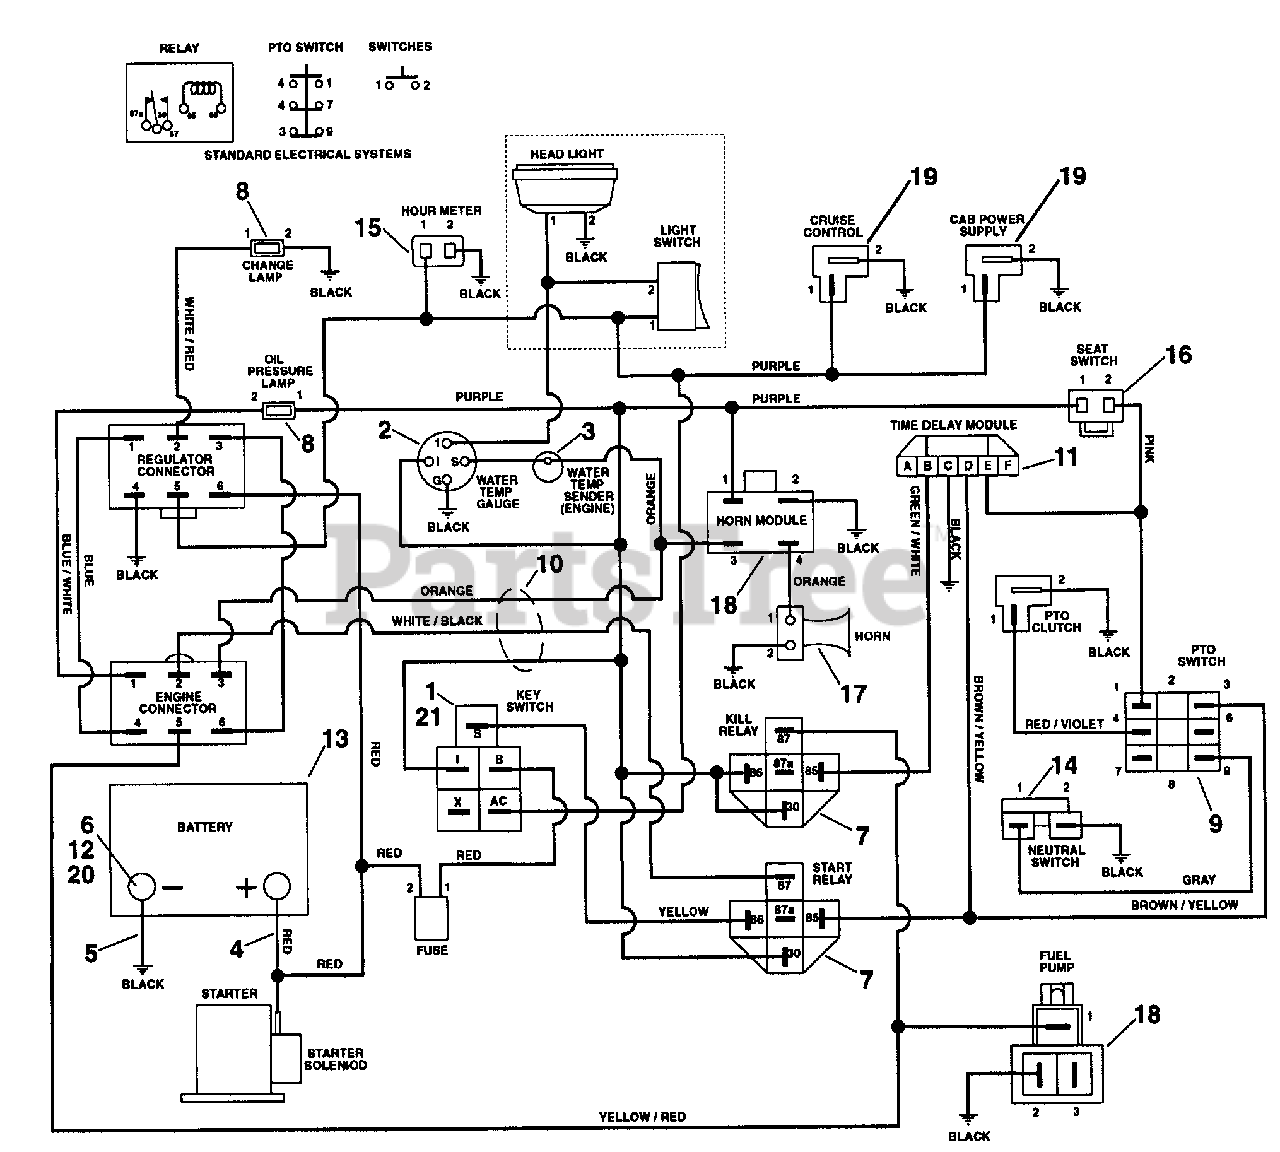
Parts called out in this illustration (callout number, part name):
1	Switch,Ignition(Gas)
2	Gauge,Temperature
3	Temperature Sender
4	Cable,Battery to Solenoid
5	Cable,Negative Battery 35.0" Lg
6	Cover,Battery Terminal
7	Relay
8	Light,Indicator
9	Switch,Clutch with Retainer Ring
10	Wire Harness - Kawasaki
11	Module, Interlock, Delay, 1801
12	Nut-Speed .25-20
13	12 Volt Battery(8 HP)
14	Switch-NeutralStart N.O.
15	Hour Meter
16	Switch-Seat
18	High Temp. Warning Module
19	Cover-Switch
20	Boot, Insulator
